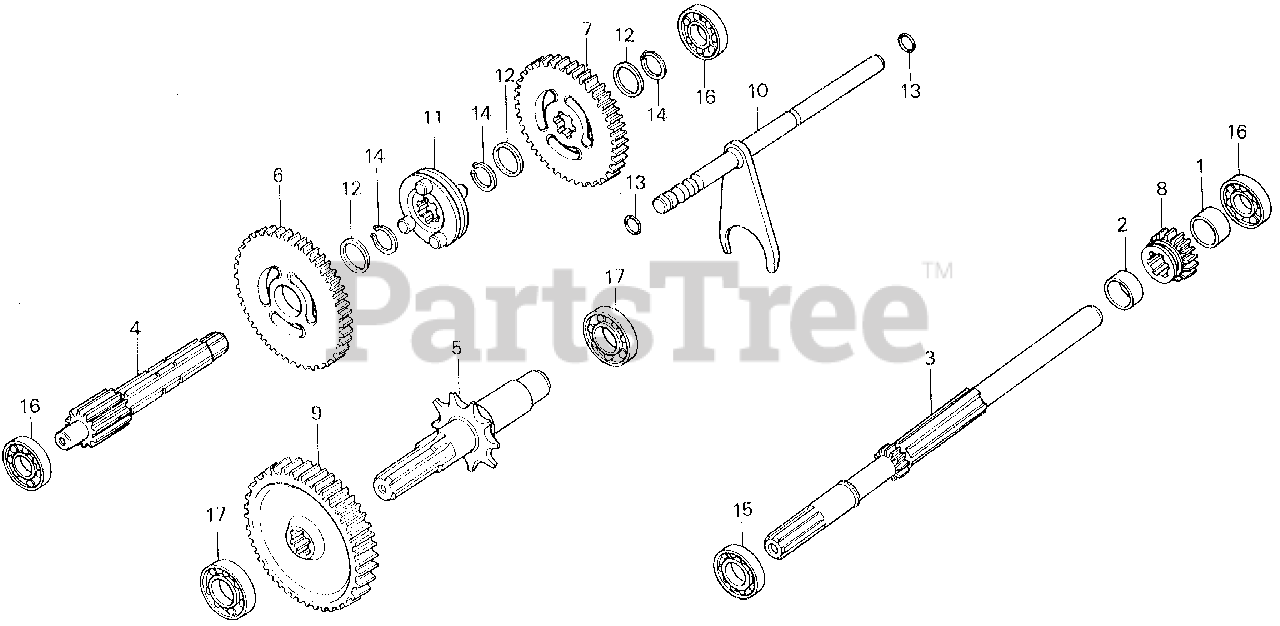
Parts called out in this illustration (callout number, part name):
1	COLLAR, GEAR LOCK A (NOT AVAILABLE)
2	COLLAR, GEAR LOCK B
3	SHAFT, INPUT
4	COUNTERSHAFT
5	SHAFT, FINAL
6	GEAR, COUNTERSHAFT FIRST
7	GEAR, COUNTERSHAFT SECOND
8	GEAR, CHANGE
9	GEAR, FINAL
10	SHAFT, SHIFT FORK
11	INSULATOR, PLATE (NOT AVAILABLE)
12	WASHER, THRUST (17MM)
13	O-RING (8.8X1.9)
14	CIRCLIP (OUTER) (17MM)
15	BEARING, RADIAL BALL (6003)
16	BEARING, RADIAL BALL (6202)
17	BEARING, RADIAL BALL (6203)
